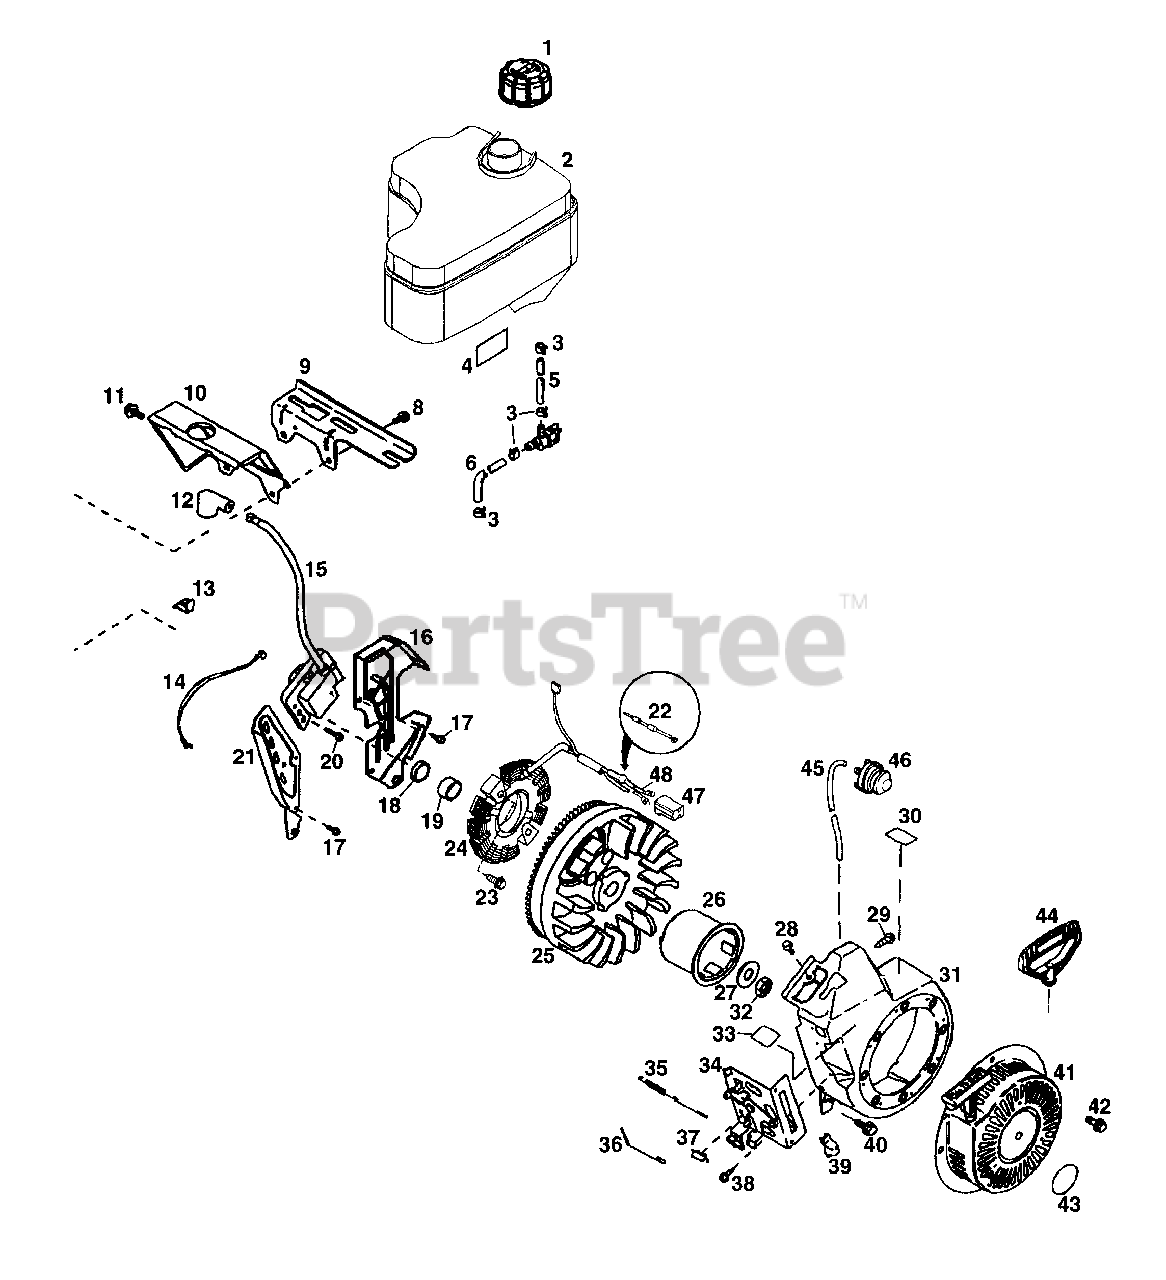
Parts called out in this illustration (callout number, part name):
1	Fuel Cap
2	Fuel Tank
3	Fuel Line Clamp
4	Instruction Decal
5	Fuel Line
6	Fuel Line
8	Screw, 1/4-20 x 7/8"
9	Fuel Tank Bracket
10	Blower Housing Extension
11	Screw, 10-24 x 9/16"
12	Spark Plug Cover
13	Wire Clip
14	Ground Wire
15	Solid State Ignition
16	Air Baffle (Right)
17	Screw, 10-24 x 9/16"
20	Screw, Torx T-15, 15/16"
21	Air Baffle (Left)
23	Screw, 1/4-20 x 3/4"
24	Alternator Coil
26	Starter Cup
27	Bell Washer
28	Screw, 1/4-20 x 31/64"
29	Screw, 10-32 x 1/2"
30	Lube Decal
31	Blower Housing
32	Flywheel Nut
33	Control Decal
34	Control Bracket
35	Extension Spring
36	Governor Link
38	Screw, 10-32 x 1/2"
39	Control Knob
40	Screw, 1/4-20 x 31/64"
41	Rewind Starter
42	Screw, 1/4-20 x 31/64"
43	Starter Decal
44	Mitten Grip Starter Handle
45	Primer Line
46	Primer Assembly
